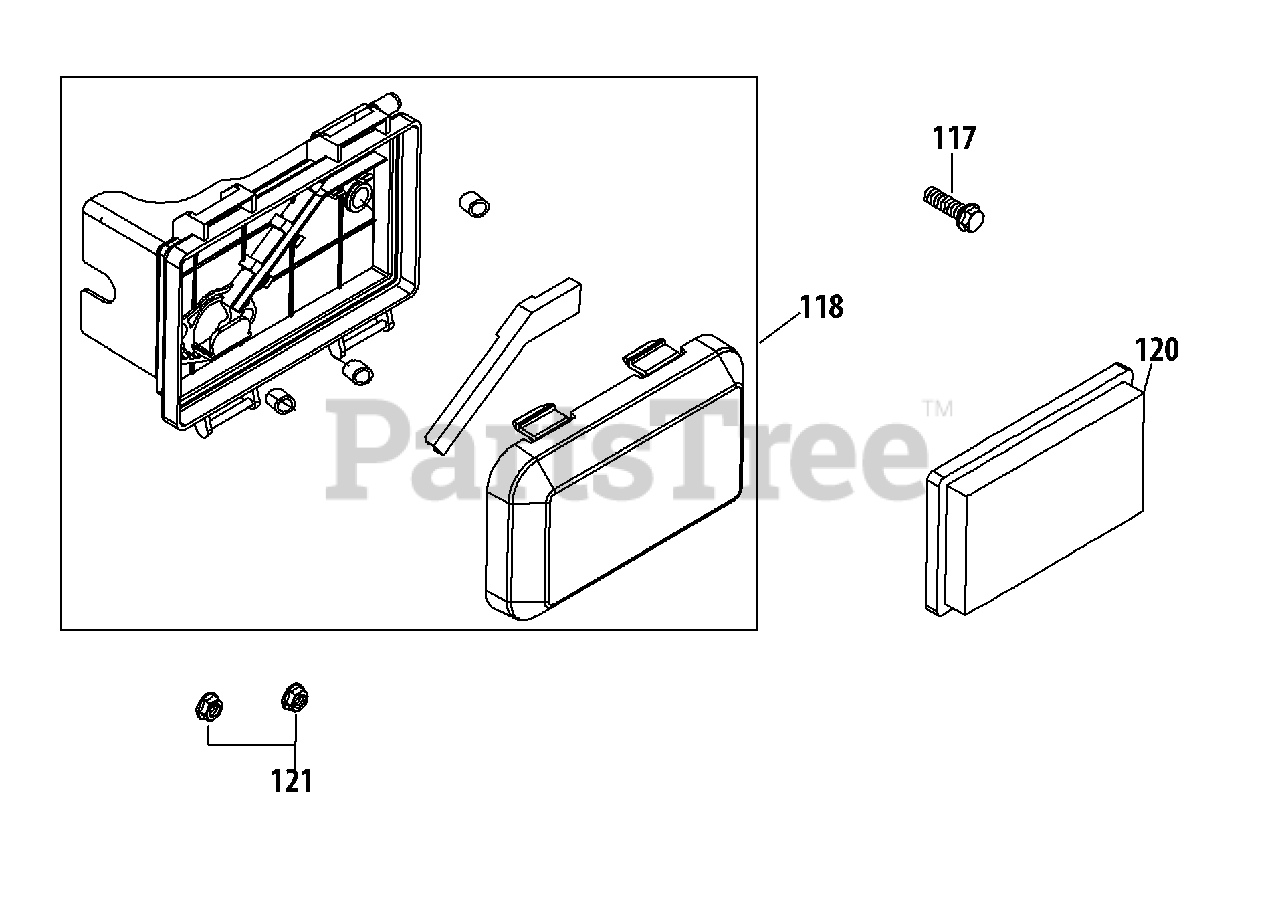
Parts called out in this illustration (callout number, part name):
117	Bolt M6X30 Af Base/Coil/E-Starter
118	Air Cleaner Housing Assembly
120	Air Cleaner Kit
121	Nut M6X10Mm Starter/Carb/Muff
